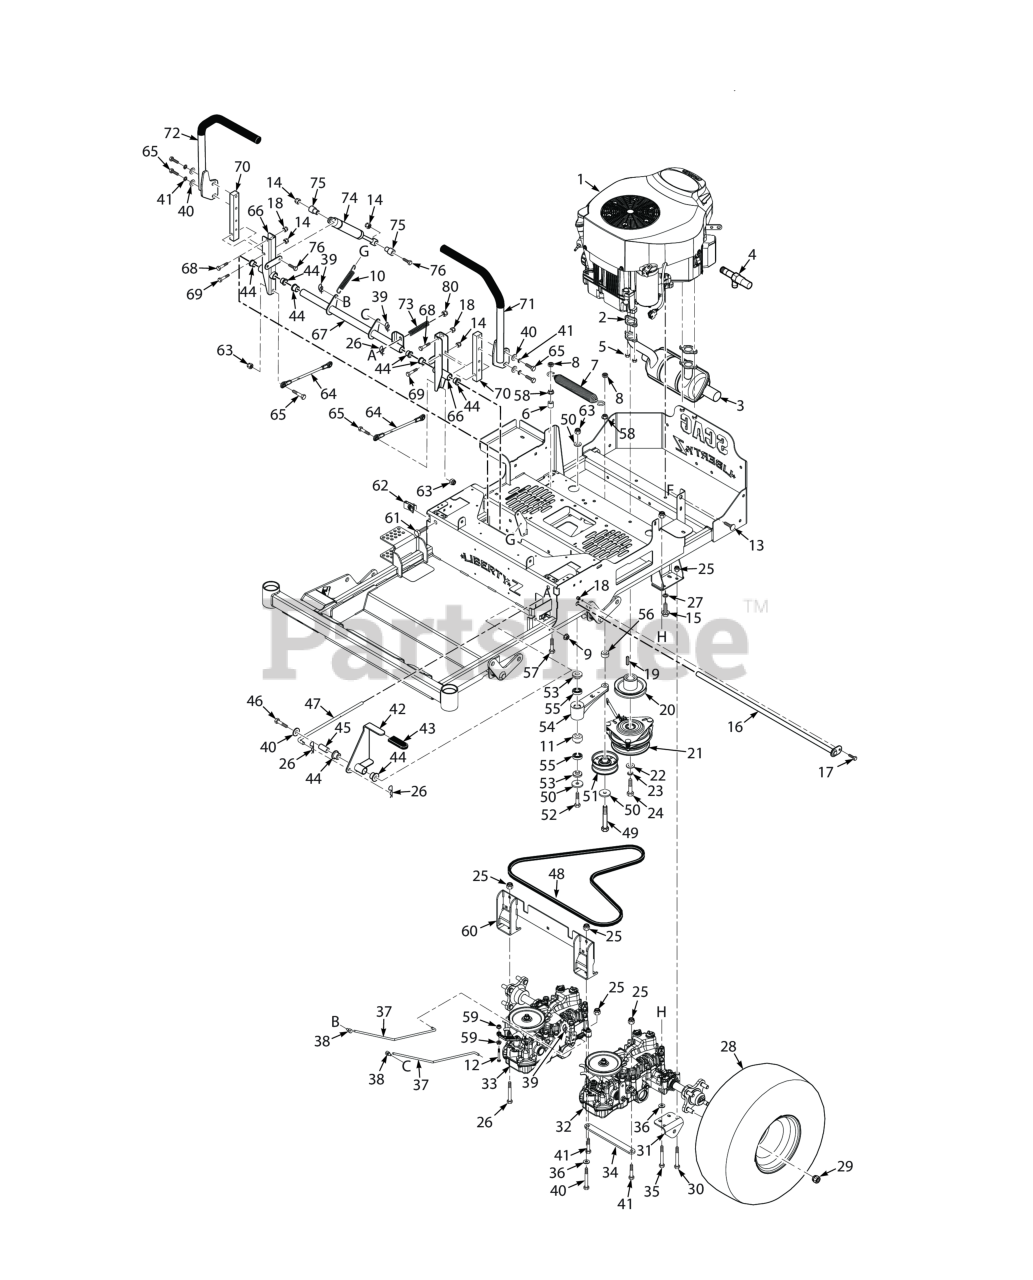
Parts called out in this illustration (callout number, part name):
1	Engine, Kawasaki 21FR
2	Gasket, Exhaust
3	Muffler, Kawasaki FR651V & FR691V
4	Oil Drain, Kawasaki
5	Nut, M8 x 1.25 Hex Special
6	Spacer, Idler Pulley - SFZ52
7	Spring, Transmission Drive
8	Bolt, Hex Head 3/8-16 x 1" Ser. Flg.
9	Nut, Flange Elastic Stop Nut, 3/8-16
10	Spring, Deck Latch
11	Spacer, Bearing
12	Bolt, Hex Head 3/8-16 x 2-1/4" - 61"
13	Serr. Fl. Hex Head CPSCR, 1/4-20 x 3/4"
14	HEX NUT, ELASTIC STOP LOCK, 5/16-18
15	Bolt, Hex Head 3/8-16 x 1-1/4", Kawasaki FX / FS
16	Shaft Weldment, Control Arm
17	BOLT, HEX HEAD, 1/4-20 X 5/8
18	HEX, NUT, ELASTIC STOP LOCK, 1/4-20
19	Key, 1/4 x 1/4 x 1.25" Pulley Mtg.
20	Pulley, 4-1/2" - 1" Bore
21	Clutch
22	Lockwasher, 7/16� Spring
23	Bolt, Hex Head 7/16-20 x 3¼" w/Patch
24	Bolt, Hex Head 7/16-20 x 2-1/4" w/Patch (Kawasaki)
25	Nut, Flange Head Elastic Stop 5/16-18
26	BOLT, HEX HEAD, 5/16-18 X 2-1/4
27	Lockwasher, 3/8" Spring, Kawasaki FX / FS
28	Wheel Assembly (48, 52)
29	Wheel Nut, 1/2-20 x 13/16
30	Bolt, Hex Head 5/16-18 x 3.00"
31	Bracket, Pusharm
32	Transaxle - Tuff Torq, LH - SZL
33	Transaxle - Tuff Torq, RH - SZL
34	Stiffener, Axle
35	BOLT, HEX HEAD, 5/16-18 X 2-1/4
36	Flatwasher, 5/16-.375 x .875 x .083 (35BV & 37BV-EFI)
37	Rod, Brake - LH
38	Joint, Swivel
39	Pin, Rue Cotter 3/8" Diameter
40	BOLT, HEX HEAD, 5/16-18 X 2-1/4
41	Bolt, Hex Head 3/8-16 x 1-3/4" (Kohler EFI)
42	Brake Lever Assembly
43	Grip, Brake Handle
44	Bearing
45	Pivot, Brake Lever
46	Capscrew, Hex Head 3/8-16 x 2-1/2"
47	Rod, Upper Brake Linkage
48	Belt, Tuff Torq Transmission-SZL
49	Capscrew, Hex Head 3/8-16 x 3-3/4"
50	Flatwasher, 3/8 (.391 x .938 x .105 HD) Grade 8
51	Pulley, 3-1/2" Dia.
52	Bolt, Hex Head 3/8-16 x 3" - 52"
53	Spacer, Controls
54	Trans. Idler Arm Assy. (Includes 24, 79)
55	BEARINGS, BALL, NEUTRAL RETURN
56	Spacer, Idler Pulley - SFZ61
57	Capscrew, Hex Head 3/8-16 x 2.0"
58	NUT, 3/8-16 SERRATED FLANGE HEX HEAD
59	NUT, 1/4-20 SERRATED FLANGE HEX HEAD
60	Mounting Weldment, Axle - Tuff Torq
61	Bolt, Hex Head 3/8-16 x 2-1/2" Soecial Lock
62	U-Nut, 3/8-16
63	HEX NUT, ELASTIC STOP LOCK, 3/8-16
64	Linkage, Pump
65	Bolt, Hex Head 3/8-16 x 1-1/4", Kawasaki FX / FS
66	Control Arm Assembly
67	Bellcrank Assembly (incl. 44)
68	Bolt, Hex Head, 1/4-20 x 1-1/4"
69	Bolt, Hex Head 5/16-18 x 1-1/2" - Front
70	Bar, Control Lever
71	Handlebar w/Grip
72	Handlebar w/Grip
73	Spring, Brake
74	Damper, Steering
75	Spacer, Pump Dampener
76	Bolt, Hex Head 5/16-18 x 1-1/2" (Right Front Engine Mounting, Briggs and Kohler Only)
